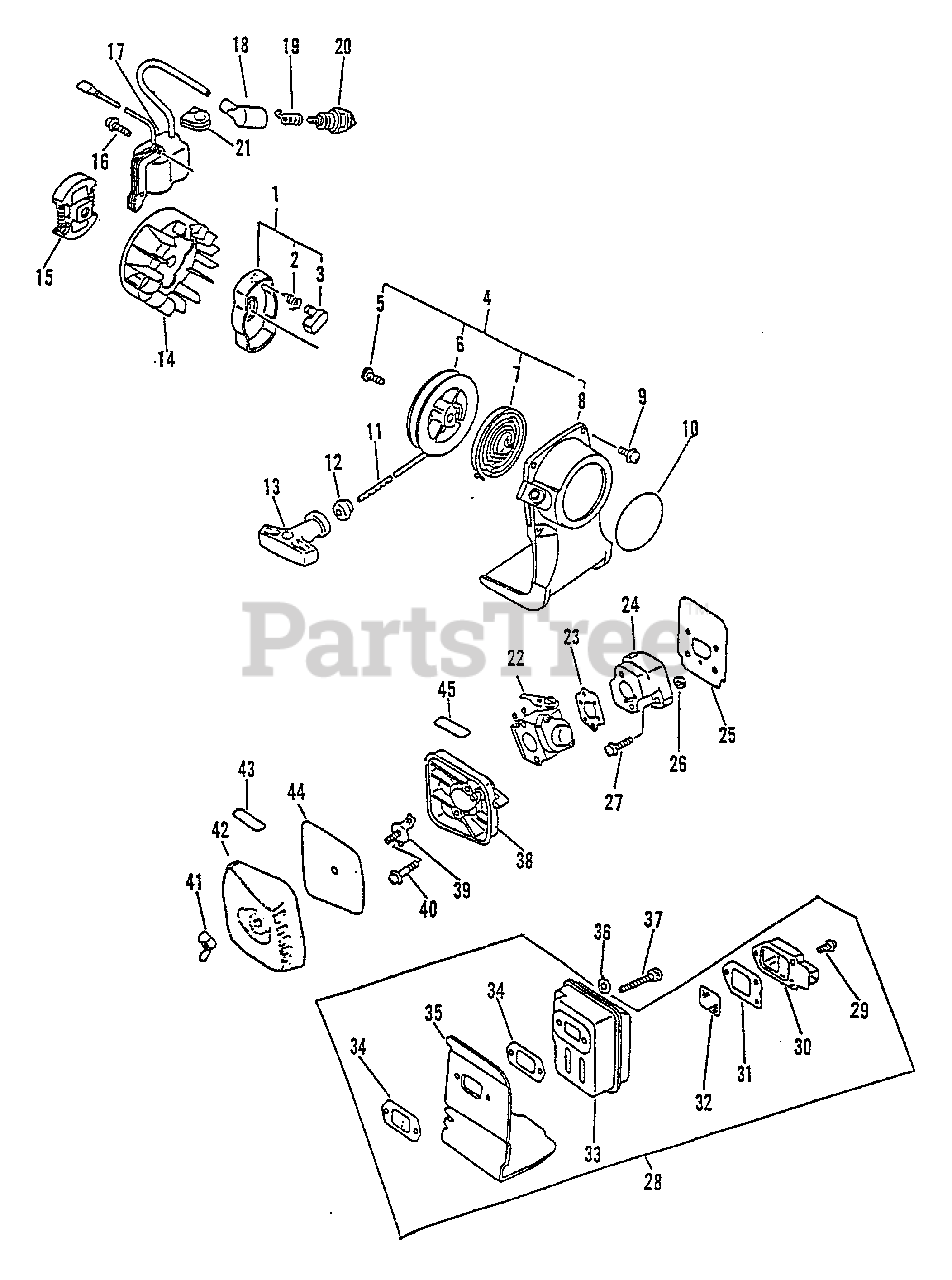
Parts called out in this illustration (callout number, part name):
1	STARTER PAWL ASSY
2	SPRING, RETURN
3	PAWL, STARTER - BLACK
4	STARTER ASSY
6	REEL, ROPE
7	SPRING, REWIND
8	CASE, STARTER - BLUE
9	SCREW - 4X16
10	LABEL - LESCO
11	ROPE, STARTER - 3X890
12	GUIDE, ROPE
13	GRIP, STARTER
14	FLYWHEEL
15	CLUTCH ASSY
16	SCREW - 4X22
17	COIL, IGNITION
18	CAP, SPARK PLUG
19	TERMINAL, SPARK PLUG CAP
20	SPARK PLUG -- BPM-7A
22	CARBURETOR C1U-K16
23	GASKET, INTAKE
24	INSULATOR, INTAKE
25	SHIELD, INTAKE
27	SCREW - 5X20
28	MUFFLER ASSY
29	SCREW - 4X10
30	GUIDE, EXHAUST - OUTER
31	GASKET, EXHAUST
32	SCREEN, SPARK ARRESTOR
33	MUFFLER
34	GASKET, EXHAUST
35	COVER, EXHAUST
36	WASHER - 5
37	SCREW - 5X55
38	CASE, AIR FILTER
39	PLATE, PREVENT
40	SCREW - 5X64
41	WINGNUT - 6
42	COVER, AIR FILTER - BLACK
43	LABEL - TOP
44	FILTER, AIR
45	LABEL - CHOKE
